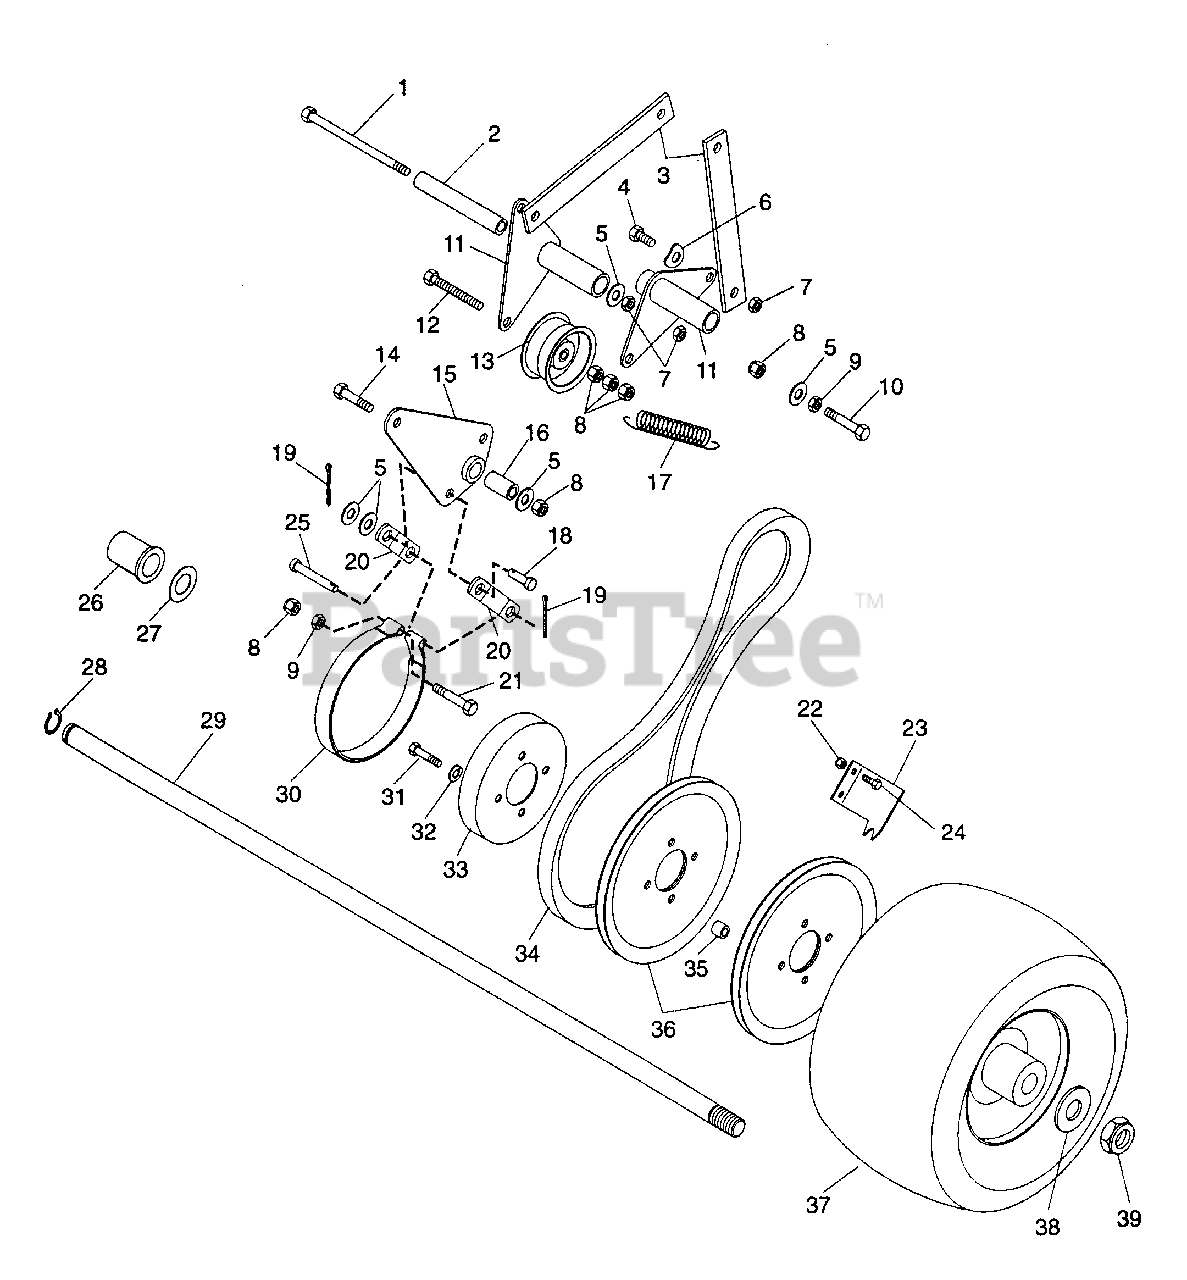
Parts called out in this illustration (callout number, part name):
1	Bolt-Hex .38-16 x 5.00
2	Bush, Steel .385 x .610 x 3.85
3	Strap, Wheel Clutch
4	Bolt-Hex .38-16 x .75 Grade 5
5	Washer-Flat-Steel .406 x .812 x .065
6	Washer-Spring .375
7	Nut-Locking-Center .625-10 Grade 2
8	Nut-Locking-Nylon .375-16 Grade 2
9	Nut-Hex .375-16 Grade 2
10	Bolt-Hex .38-16 x 2.25 Grade 5
11	Weldment, Wheel Clutch Arm
12	Bolt-Hex .38-16 x 3.0 Grade 5
13	Sheave 3.25 x 1.25
14	Bolt-Hex .38-16 x 2.00 Grade 5
15	Weldment, Brake Arm
16	Bushing, Sleeve .391 x .622 x .950
17	Spring-Tension .069 x .62 x 3.50
18	Pin-Clevis .38 x .594
19	Pin-Cotter .12 x .75
20	Link, Brake Arm
21	Bolt-Hex .38-16 x 2.00 Grade 5
22	Nut-Locking-Nylon .312-18 Grade 2
23	Cleaner, Pulley Groove Left Hand
23	Cleaner, Pulley Groove Right Hand
24	Bolt-Hex .31-18 x .625
25	Pin-Clevis .372 x 1.25
26	Bushing-Flange 1.010 x 1.38 x 1.4 x 1.65
27	Washer-Thrust 1.55 x 1.002 x .093
28	Ring-Retaining-External .906 x .078
29	Shaft, Axle
30	Assembly, Brake Band, Pro
31	Bolt-Hex .31-18 x 1.50 Grade 5
32	Washer-Lock External .375 x .050
33	Drum, Brake
34	V-Belt, Wheel Drive Set (2)
35	Bushing, Sleeve .385 x .625 x .475
36	Pulley-V 9.00 x 3.75
37	Tire/Wheel Assembly 13 x 6.50-6
38	Washer-Flat-Steel .813 x 1.370 x .100
39	Nut, Locking 3/4-10
